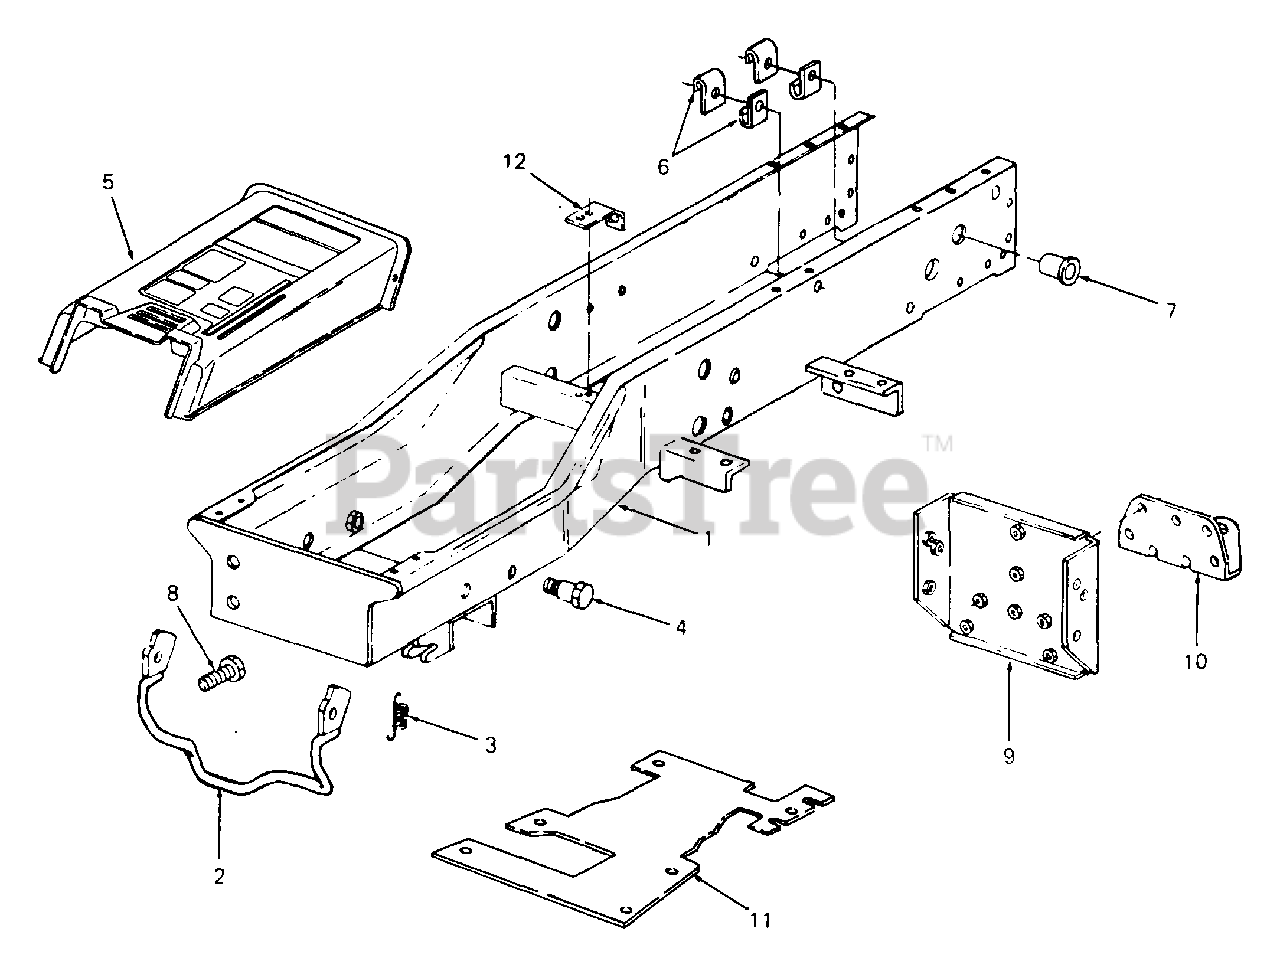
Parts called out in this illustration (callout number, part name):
3	Spring, Latch
4	Bolt, Shoulder
5	Cover, Frame
6	Clip, Cable
7	Bushing, Snap
8	Screw, Adjustment, 1/2-20 x 1.0 Lg GR5
9	Plate Assy, Hitch
11	Baffle, Lower Frame
12	Bracket, Switch
